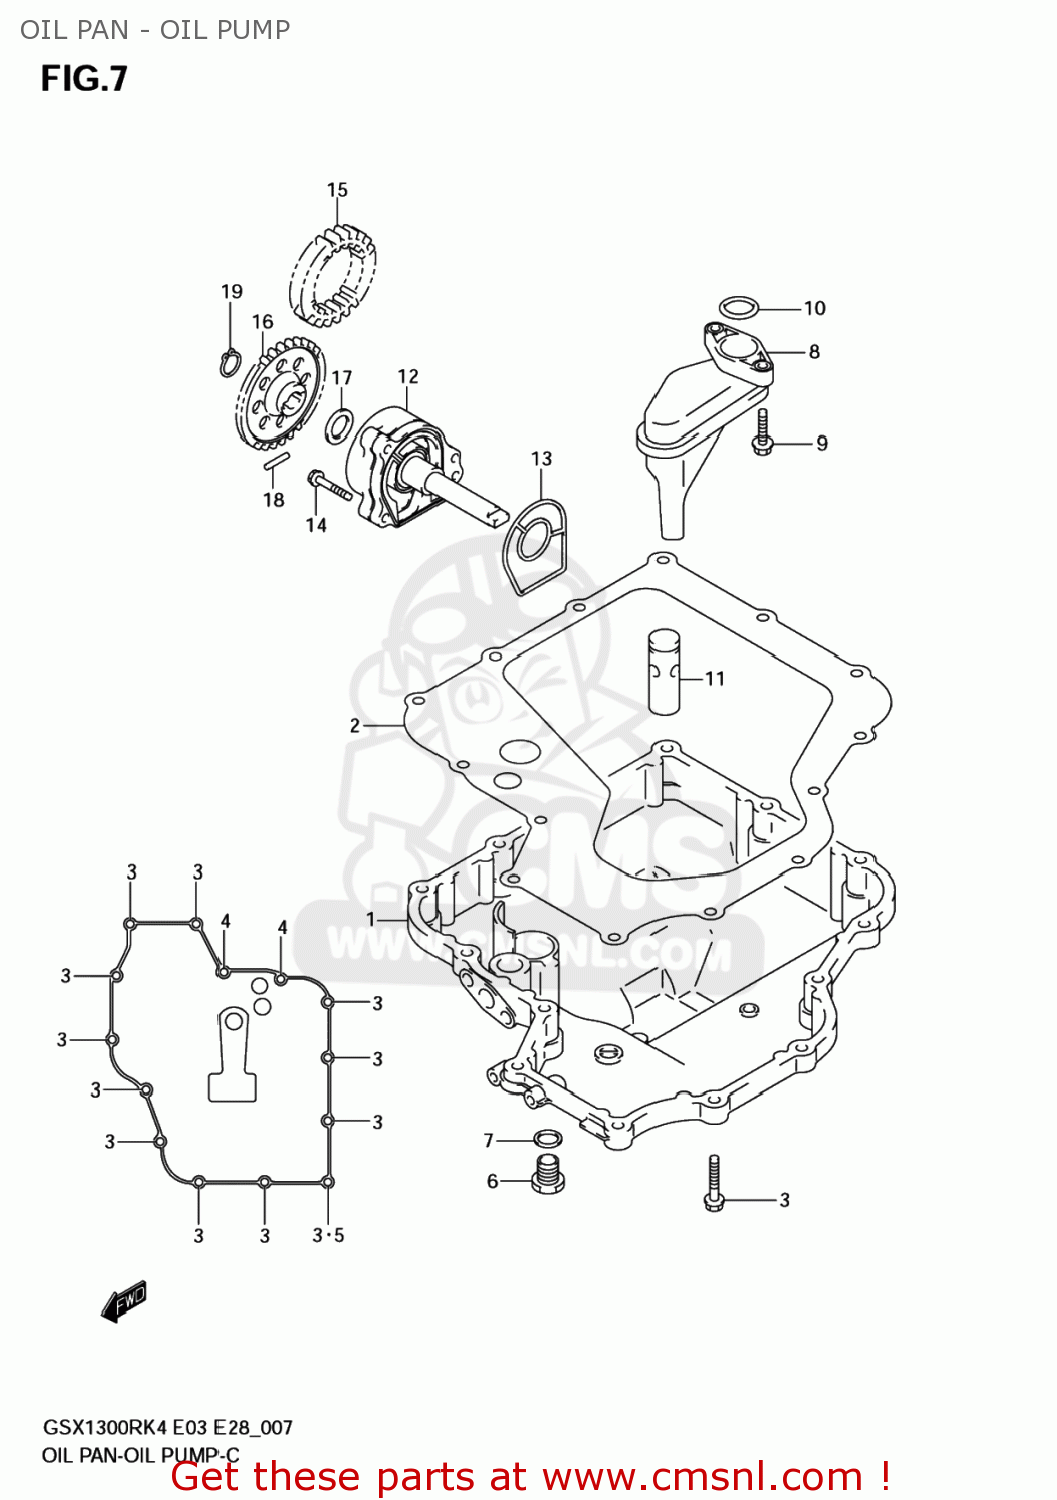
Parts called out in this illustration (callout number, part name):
1	PAN,OIL
2	GASKET,OIL PAN (NAS)
3	BOLT,G/S SWITC
4	BOLT
5	GASKET(5.8X13X1.2) (NAS)
6	PLUG(14X20)
7	GASKET(13.8X18.8X4.8) (NAS)
8	STRAINER,ENGINE OIL
9	BOLT
10	O RING(D:2.62,ID:20.3)
11	VALVE ASSY,OIL RELIEF(7K)
12	PUMP ASSY,ENGINE OIL
13	O RING,OIL PUMP
14	BOLT,G/S SWITC
15	GEAR,OIL PUMP DRIVE
16	GEAR,OIL PUMP DRIVEN
17	SHIM(12X20X0.5)
18	PIN(5X18)
19	CIRCLIP,12 MM
